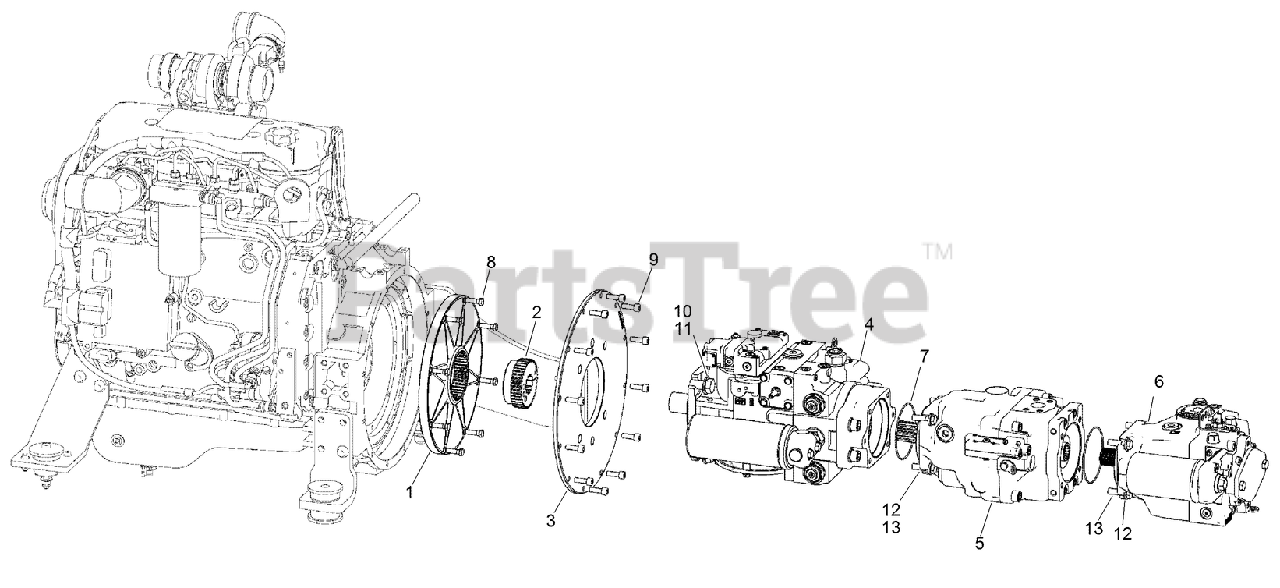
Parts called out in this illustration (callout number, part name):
1	COUPLING-DRIVE, NYLON
2	HUB-STEEL, 13T
3	PLATE-MOUNT, PUMP
4	ROTARY PUMP ASM
5	LOAD-SENSE PUMP ASM
6	HYDROSTAT PUMP ASM
8	BOLT
9	SCREW-HSH
12	WASHER-FLAT
13	BOLT-Hex Hd 1/2 x 1-3/4 GR5 ZND
